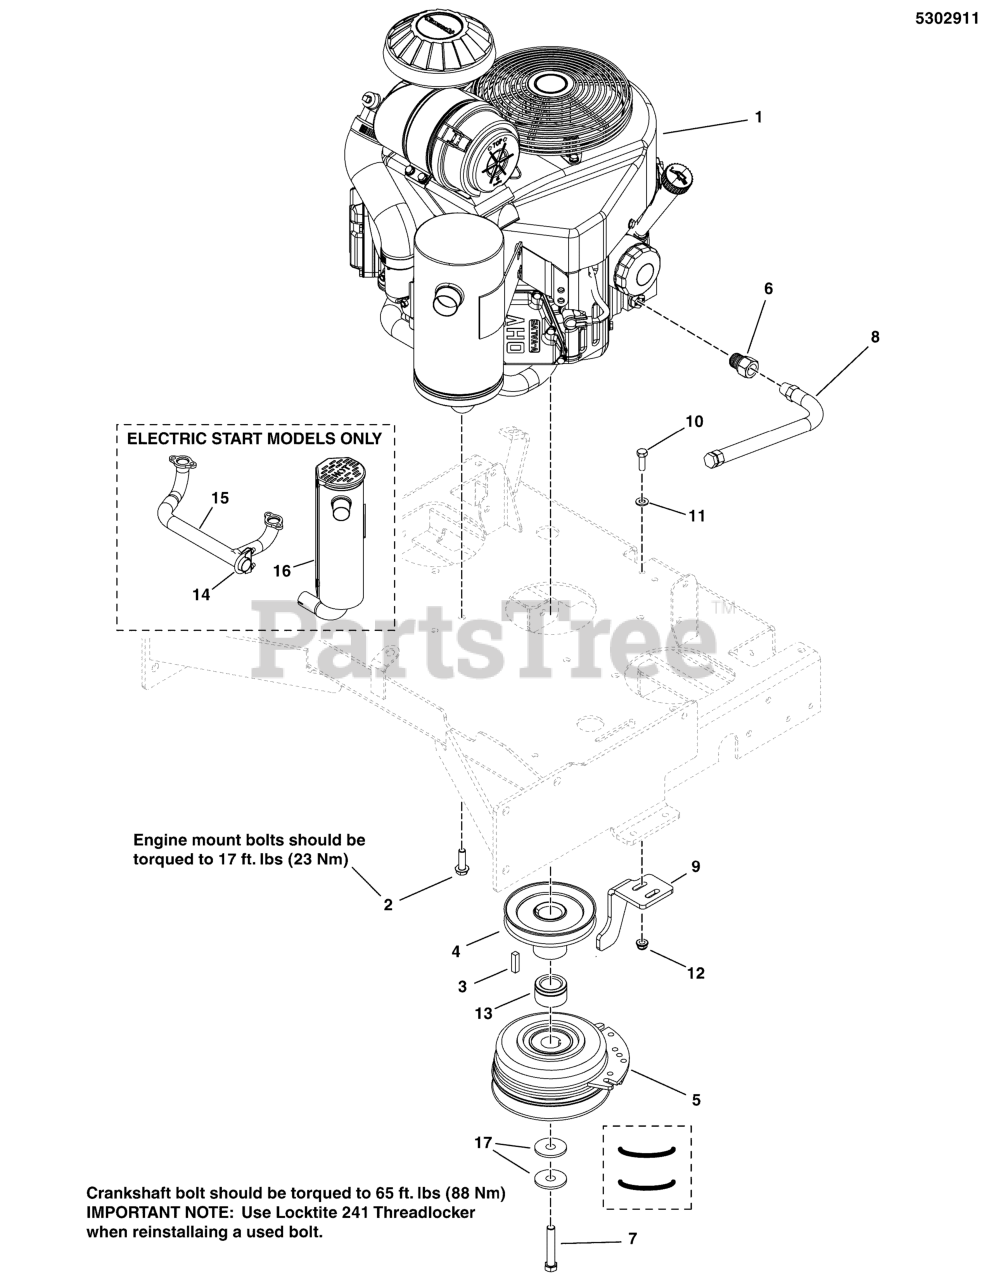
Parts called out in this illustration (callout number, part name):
1	ENGINE, KAWASAKI
2	BOLT,HEX FLG,SER GD5 3/8-16X1-1/4PACH CZ
3	KEY, 1/4 SQ X 1
4	PULLEY, CRANKSHAFT, 1.125 ID X 4.50 OD
5	* CLUTCH, 5218-134, WARNER
6	ADAPTER-OIL DRAIN
7	BOLT, CRANKSHAFT,7/16-20X2-3/4, GD8
8	HOSE, OIL DRAIN
9	PLATE, CLUTCH ANCHOR - RED
10	BOLT, 5/16-18 X 1 GD5 YZ
11	WASHER, 5/16" SAE
12	NUT, 5/16-18 HEX NYLOCK FLANGE
13	SPACER, 1.13 X 1.75 X 1.03, CZ
14	CLAMP, MUFFLER
15	MANIFOLD, KAWI, OIL FILTER SIDE
16	MUFFLER, KAWI, OIL FILTER SIDE
17	BELLEVILLE WASHER 1.1875 X .442 X .089
22	WIRE LOOM, 3/8ID X 28.00"
23	TIE, SELF-LOCKING, 12"
